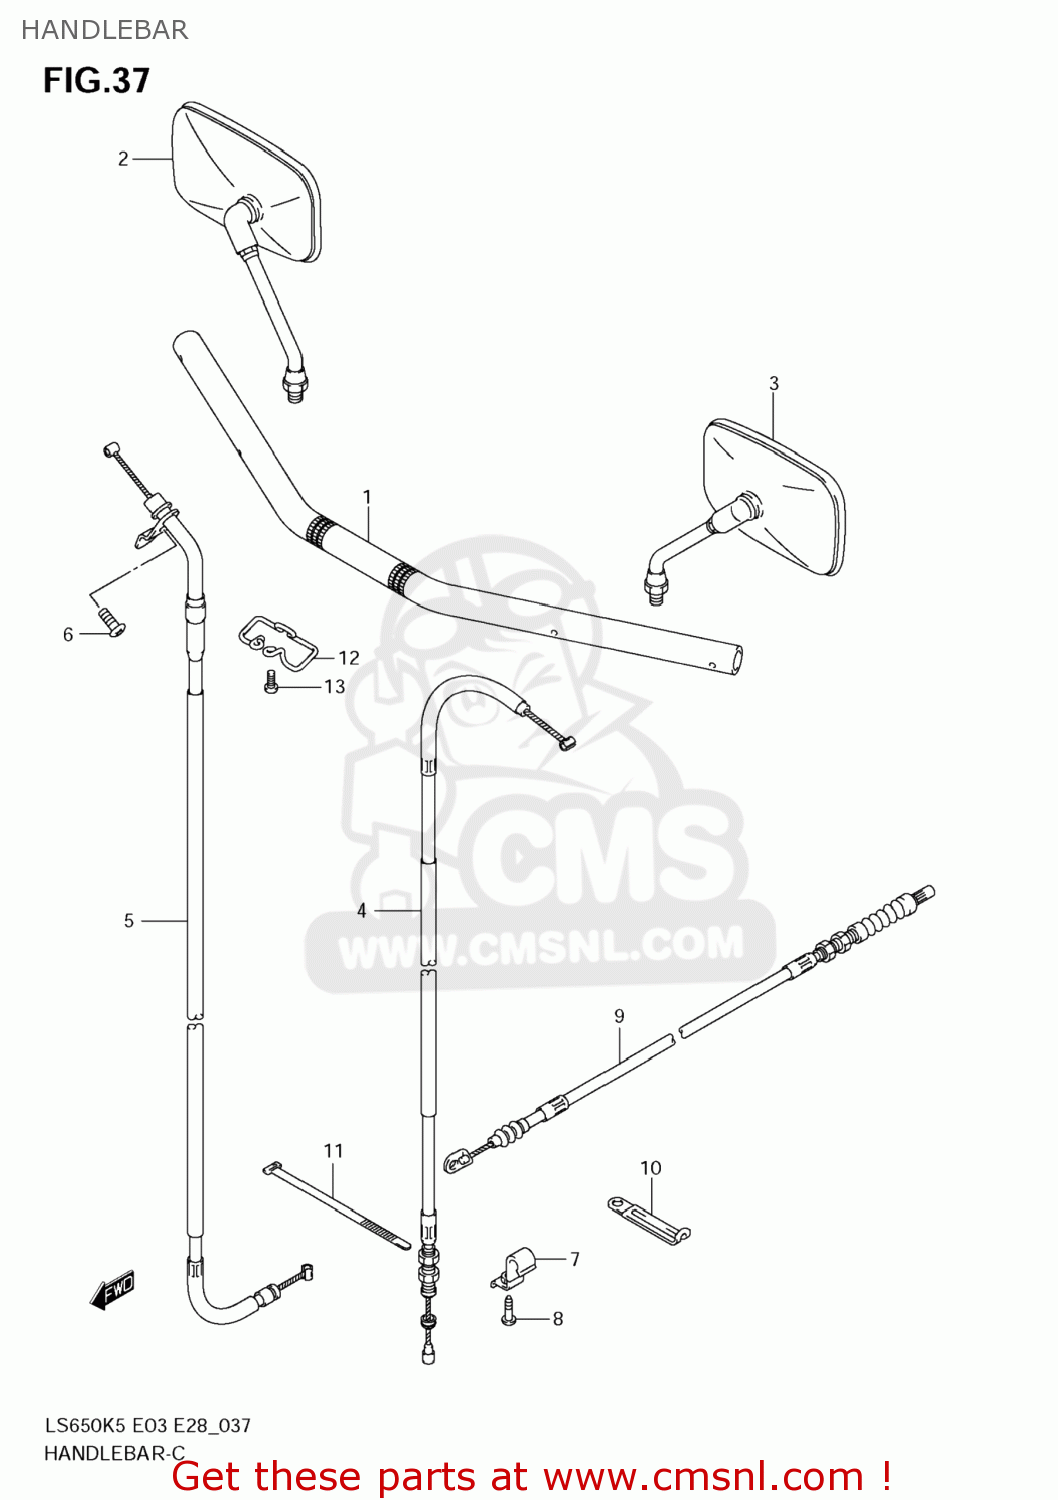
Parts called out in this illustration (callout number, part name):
1	HANDLEBAR
2	MIRROR ASSY,RR VIEW,R
3	MIRROR ASSY,RH
4	CABLE ASSY,CLUTCH
5	CABLE ASSY,THROTTLE
6	SCREW
7	CLAMP,STOP LAMP SWITCH CABLE
8	BOLT
9	CABLE,STOP LAMP SWITCH
10	CLAMP(L:65)
11	CLAMP(L:145)
12	GUIDE,CABLE
13	SCREW(5X10)
